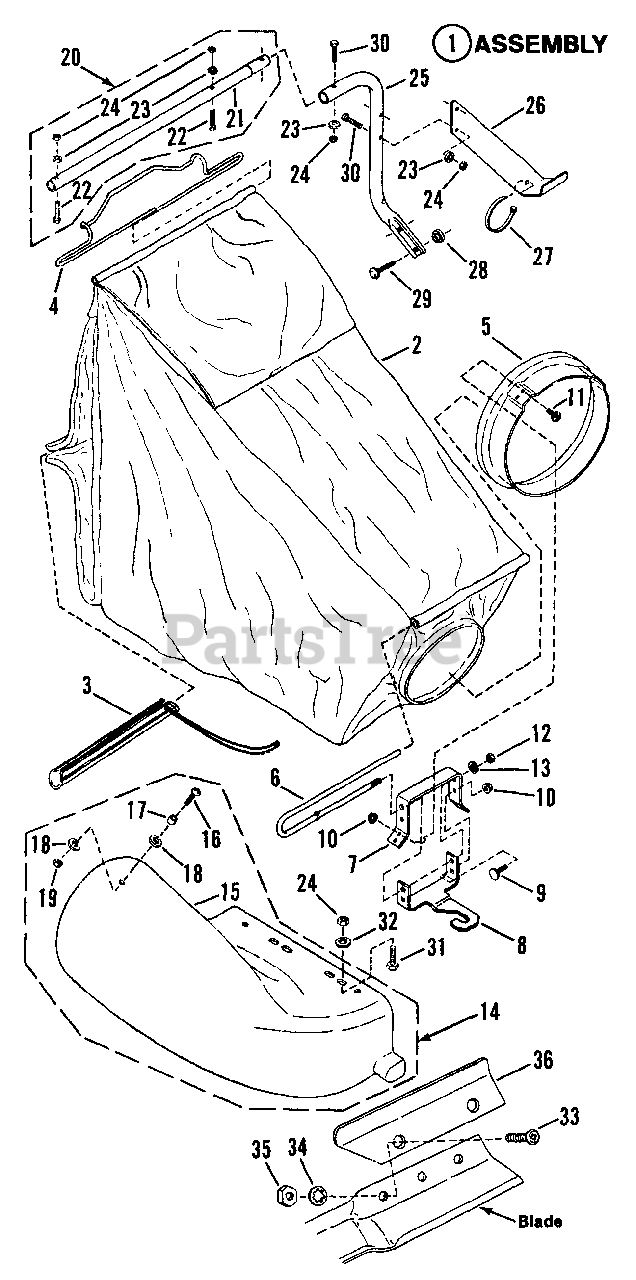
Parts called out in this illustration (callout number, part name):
1	BAG ASSM'Y., Grass
2	BAG, Grass
3	SLIDER, Grass Bag
4	WIRE, Support, Bag, Rear
5	ADAPTER, Bag, Front
6	WIRE, Bag, Front
7	ADAPTER, Handle
8	LATCH, Chute
9	BOLT, 1/4-20 x 5/8" Fl. Hd. Ca.
10	NUT, 1/4-20 Flange Lock
11	BOLT, 1/4-20 x 3/4" Short Neck Carriage
12	NUT, 3/8-24 Hex
13	WASHER, 3/8 Int. Tooth Lock
14	ADAPTER ASSM'Y., Deck
15	CHUTE ASSEMBLY
16	SCREW, 1/4-20 x 3/4", Slotted Rnd. Hd. M.
17	SPACER
18	WASHER, 5/16" I.D.,1" O.D.
19	NUT, 1/4-20 Hex, Center Lock
20	SUPPORT ASSM'Y., Bag, Rear
21	TUBE, Support, Rear Bag
22	BOLT, 1/4-28 x 1-1/4"
23	WASHER, 1/4 Int. Tooth Lock
24	NUT, 1/4-28 Hex
25	SUPPORT, Tube, Rear Bag
26	BRACKET, Support
27	CABLE-TIE
28	ROLLER
29	BOLT, 5/16-18 x 2-1/2" Carriage
30	SCREW, 1/4-28 x 1-3/8" H.H.C.
31	SCREW, 1/4-28 x 3/4" H.N. Cap
32	WASHER, 1/4 Flat
33	SCREW, 5/16-24 x 21/32" Mach.
34	WASHER, 5/16 Int. Tooth Lock
35	NUT, 5/16-24 Hex
36	AIR LIFT
